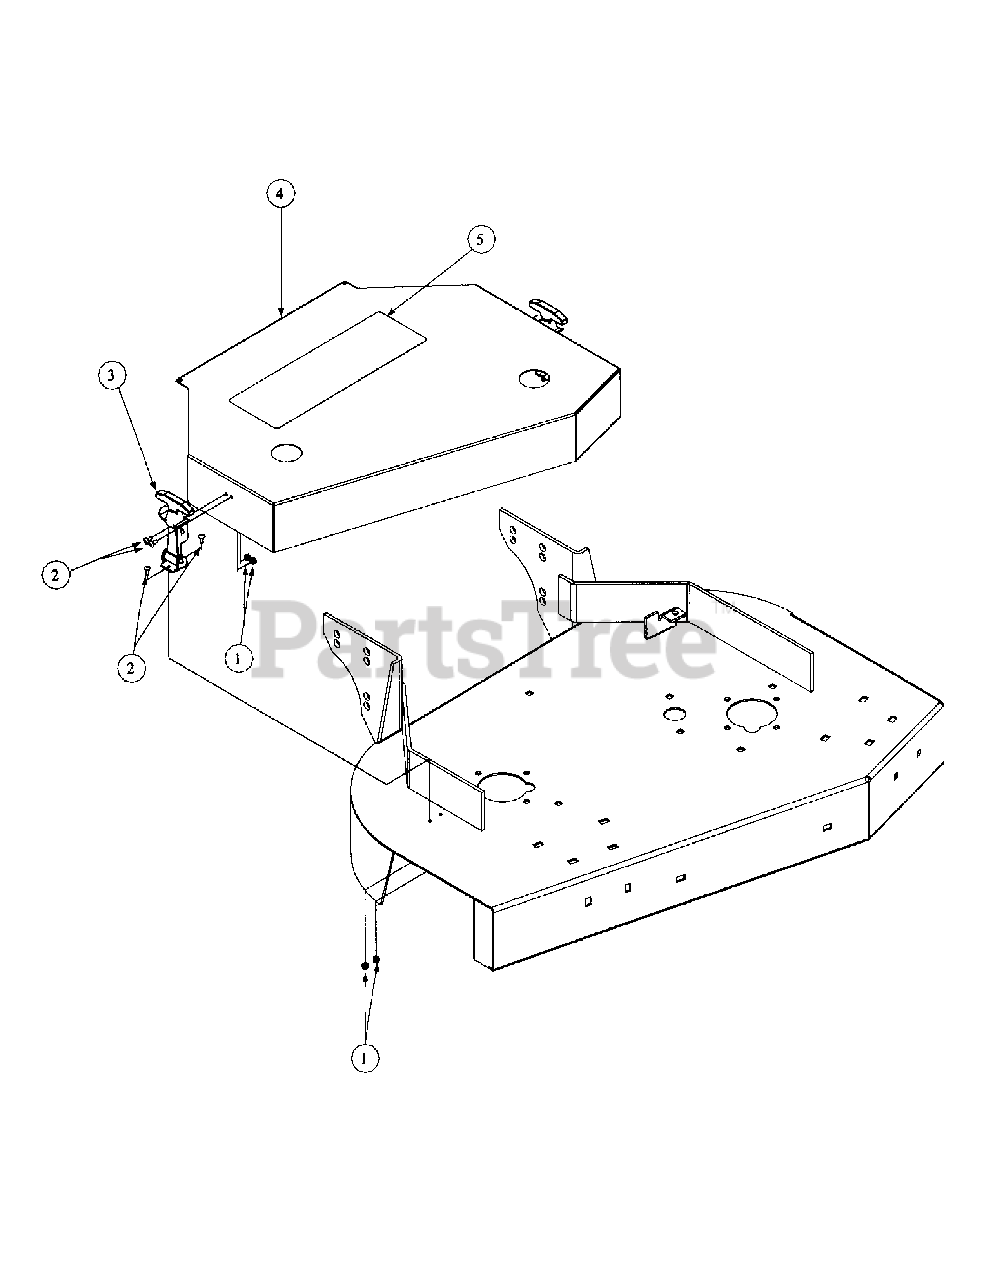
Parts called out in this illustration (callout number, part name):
1	Lock Nut, Nylon Insert
2	Machine Screw, 10-24 x 1/2
3	Rubber Hood Latch
4	Deck Cover, 36
5	Decal 36" MTD
